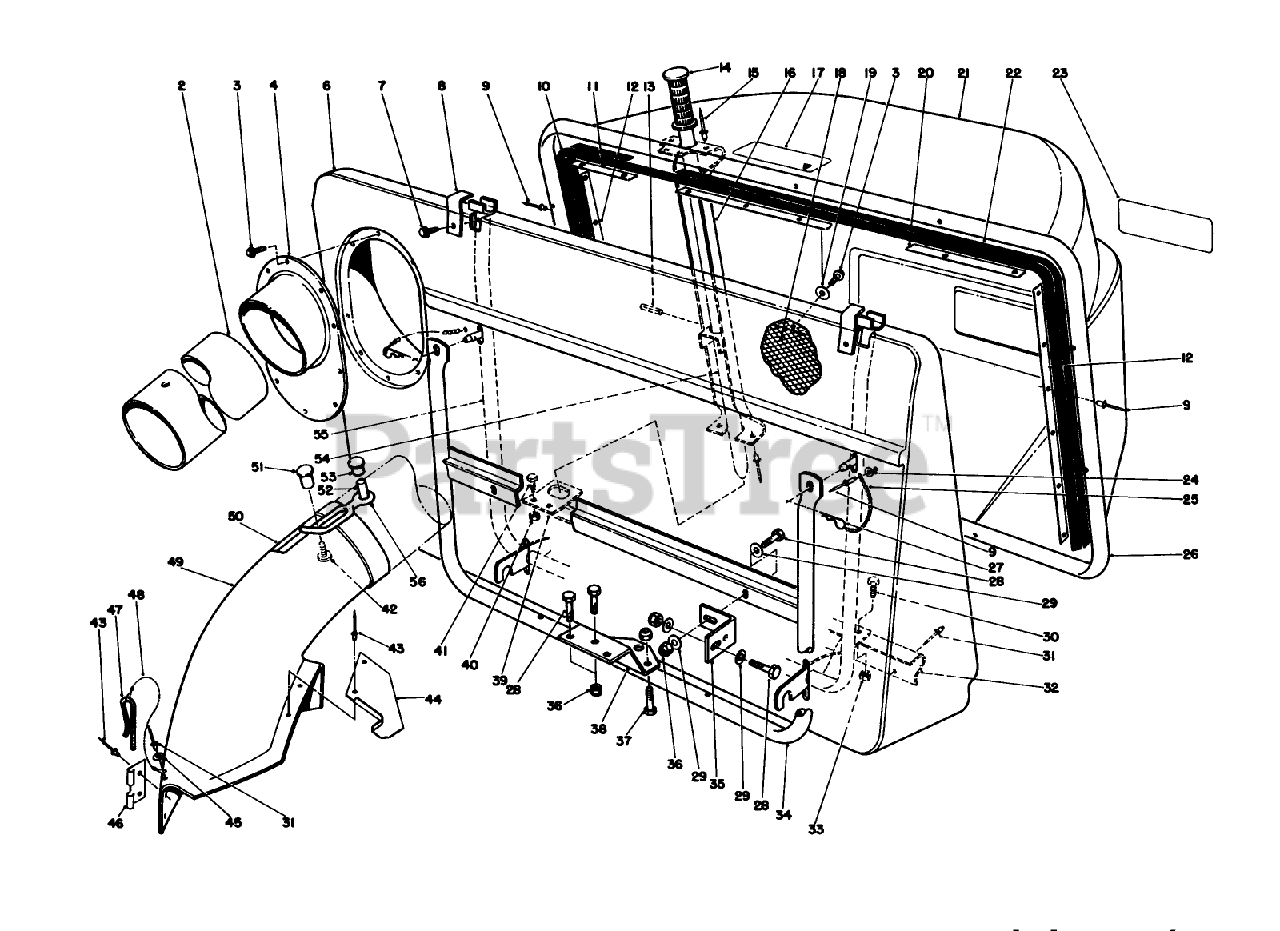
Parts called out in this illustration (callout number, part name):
3	SCREW-HWHTF
4	DUCT ADAPTER
7	SCREW-HWH
10	RH BAG SEAL
13	PIN-ROLL
15	RIVET-POP
19	WASHER-FLAT
24	WASHER
27	PIN-HAIR
28	SCREW-HH
29	WASHER-PLAIN
30	SCREW-HH
31	RIVET-BLIND
33	NUT-LOCK, CONE
34	BAG SUPPORT WA *
36	NUT-LOCK, NI
37	SCREW-HH
38	MTG PLATE *B
40	NUT-LOCK, CONE
41	SCREW-HH
43	RIVET-BLIND
44	CHUTE SUPT BRKT
45	WASHER-PLAIN
46	BRACKET-MOUNTING, CHUTE
47	PIN-LOCKING, CHUTE
48	LANYARD
49	CHUTE ASM
52	SPACER-INTERLOCK
53	FASTENER-PANEL
54	DUMP HANDLE ASM
56	RETAINER-DUCT
